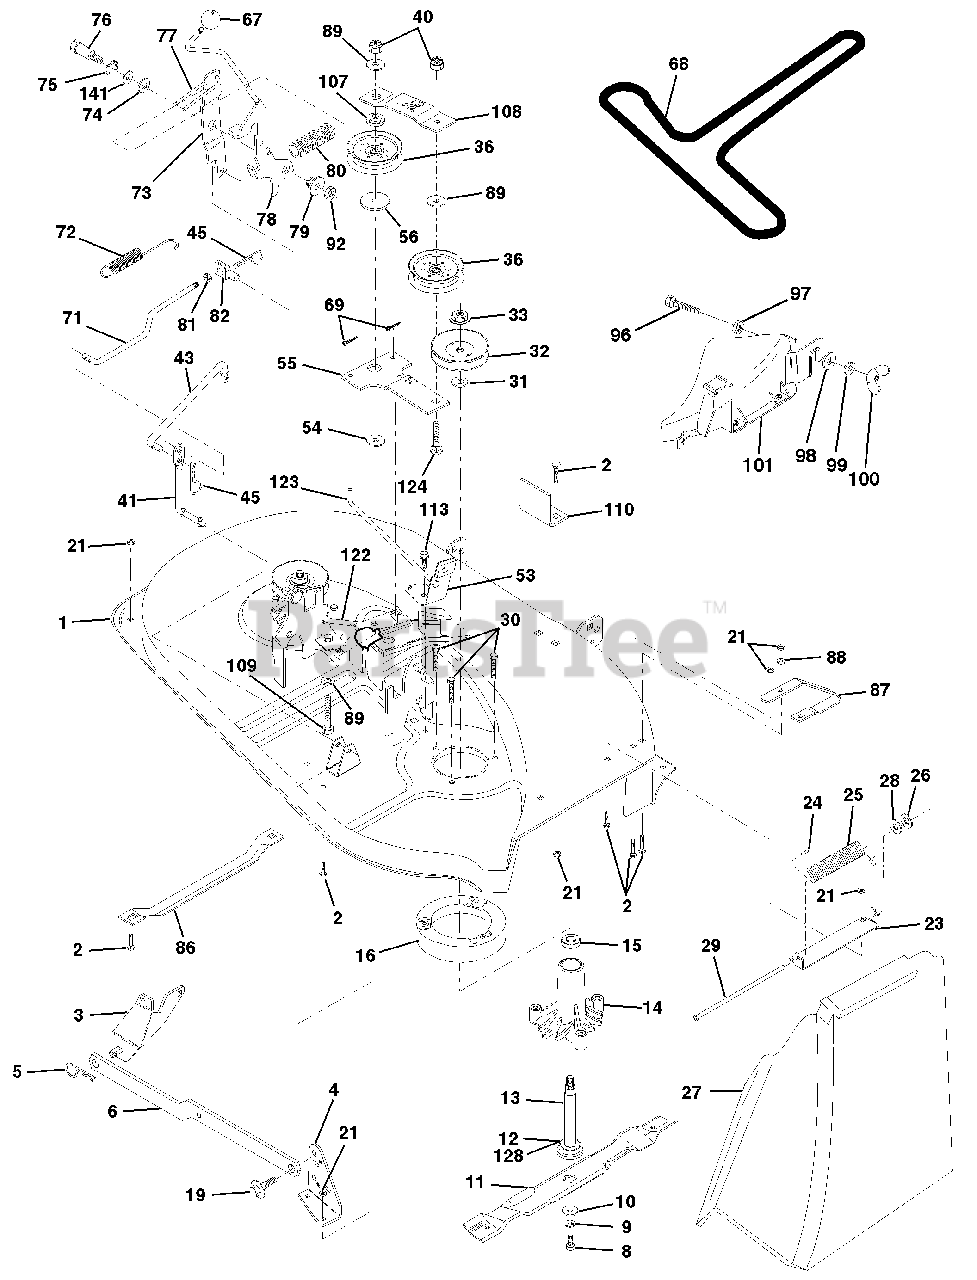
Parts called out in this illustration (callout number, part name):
1	Deck Asm Weldment
2	Bolt Rdhd Sqnk 5/16-18unc X3/4
3	Bracket Asm Fr Sway Bar 38/42
4	Bracket Asm Deck Sway Bar
5	Retainer Spring
6	Arm Suspension Rear
8	Bolt 3/8 - 24 X 1.25 Gr 8
9	Washer Lock Hvy 3/8
10	Washer Hard Blade Mower Vented
11	Blade Mower Mulching 38"
12	Bearing Ball #6024 (Mandrel)
13	Shaft Asm W/lower Bearing
14	Housing Mandrel Vented
15	Bearing Ball Mandrel
16	Stripper Mower Vented
19	Bolt Shoulder
21	Nut Crownlock 5/16-18 UNC
23	Bracket Deflector Mower
24	Cap Sleeve 80x 112 Blk Mower
25	Spring Torsion Deflector 2 52
26	Nut Push Phos & Oil
27	Shield Deflector
28	Washer 11/32 X 5/8 X 16 Ga
30	Screw Thd Rolling Washer Head
31	Washer Spacer Mower Vented
32	Pulley Mandrel
33	Nut 9/16 Toplock Flng Oil Dip
36	Pulley Idler Flat 3 060
40	Nut Crownlock 3/8-16 UNC
41	Rod Pivot W/nibs
43	Rod Clutch Secondary
45	Spring Retainer 1" Zinc/cad
54	Washer Hardened
56	Spacer Retainer Pm Mower
67	Knob Rd 7/16-14 Plastic Thds Blk
68	V-Belt Mower
69	Pin, Cotter 3/32 x 3/4
71	Rod Clutch Primary 38/42
72	Spring Return
73	Arm Clutch Secondary
74	Washer 25/32 X 1-5/8 X 16 Ga
75	Ring Klip #t5304-75
76	Bolt Shoulder 3/8-16 Unc 1 44
77	Keeper Spring 4 000
78	Arm Asm Clutch Primary
79	Bushing 747 Od X 794 Lg Brass
80	Spring Clutch Mower
81	Nut Hex Jam 3/8-16
82	Trunnion Adj 94
86	Runner, LH
87	Runner, RH
88	Washer 11/32 x 3/4 x 16 Ga.
89	Washer 13/32 x 1 x 12 Ga.
92	Nut Lock Hex W/Ins 3/8-16 Unc
96	Bolt 3/8-16 x 1-1/4 Mulcher
97	Nut Crownlock 3/8-16 UNC
98	Washer 13/32 x 1-1/4 x 16 Ga.
99	Washer Lock Hvy Hlcl Spr 3/8
101	Cover Asm Mulching 38"
107	Spacer, Retainer
108	Stiffener, Idler Arm
109	Bolt, Hex Head 3/8-16 x 2-1/2
110	Upstop Deck Front 38"
113	Screw Thdrol 5/16-18 X 3/4
122	Rod, Brake, LH
123	Rod, Brake, RH
124	Bolt, Carriage 3/8-16 x 1-3/4
128	Washer Felt
129	Washer 13/32 x 13/16 x 12 Ga.
130	Bolt, Fin Hex 3/8-16 UNC x 1 Gr. 5
131	Bolt, Rdhd Sqnk 3/8-16 x 1
141	Washer Thrust .75 x 1.230
